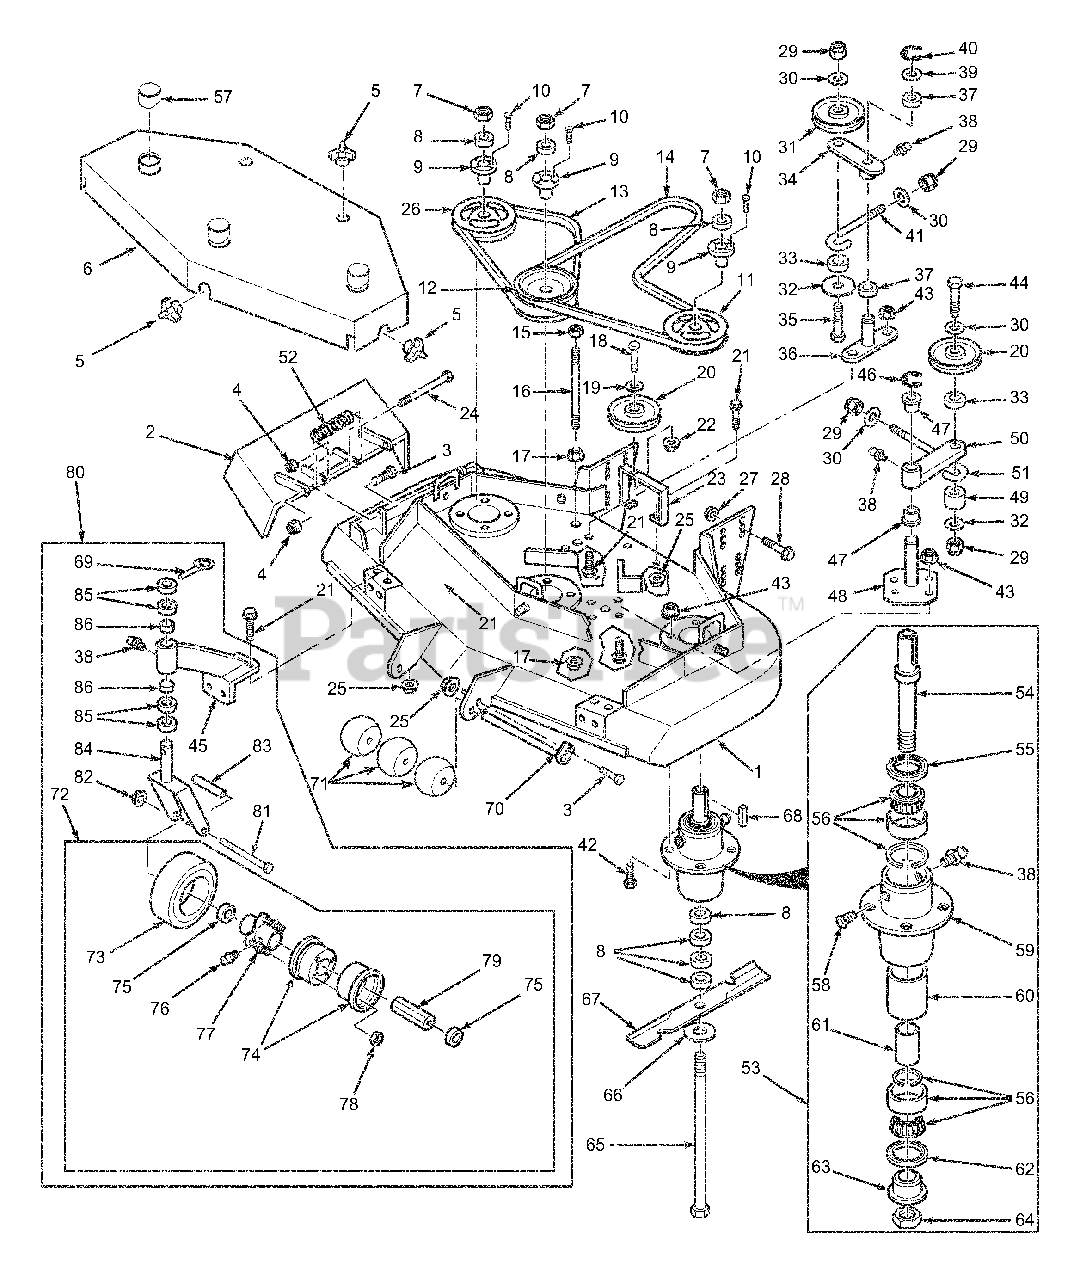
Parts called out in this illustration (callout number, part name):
1	Cutter Deck, Advantage
2	Discharge Chute, Advantage
3	Bolt, 5/16-18 x 1" Hex Head
4	Nut, 5/16-18 Elastic Stop
5	Wing Nut, 3/8-16
6	Belt Cover
7	Nut, 5/8-11 Hex Head
8	Spacer, Cutter Blade
9	Tapered Hub, 1.125 Bore
10	Bolt, 1/4-20 x 3/4 Hex Head
11	Pulley, 6.35 O.D.
12	Pulley, Double Groove, 6.35/5.75 O.D.
13	Belt, R.H. Blade Drive
14	Belt, Deck Drive
15	Lock Nut,3/8-16 Hex Head
16	Stud, 3/8-16 x 6-3/4"
17	Nut, 3/8-16 Serr. Flange
18	Bolt, 3/8-16 x 2-1/4"
19	Flatwasher, 3/8 (.391 x .938 .105)
20	Pulley, Belt Guide
21	Capscrew, 5/16-18 x 3/4 Ser. Flg. HH
22	Nut, 3/8-16 Elastic Stop
23	Idler Pulley Support
24	Bolt, Hex Head 5/16-18 x 4-1/4"
25	Nut, 5/16-18 Ser. Flg. Hex Hd.
26	Pulley, 5.75
27	Nut, 1/2-13 Ser. Flg. Hex Hd.
28	Capscrew, 1/2-13 x 1-1/4 Ser. Flg.
29	Nut, 3/8-16 Elastic Stop
30	Flatwasher, 3/8 (.391 x .938 x .105)
31	Pulley
32	Flatwasher, 3/8 (.375 x 1.50 x .060)
33	Spacer
34	Idler Arm
35	Bolt, 3/8-16 x 2-1/4"
36	Idler Pivot
37	Bushing, Bronze Oilite-3/4 ID
38	Grease Fitting, Str. 1/4-28 Self Tap.
39	Flatwasher, 3/4 (.776 x 1.25 x .059)
40	Retaining Ring, .75 EXT 'E'
41	J-Rod Idler Pulley
42	Bolt, 5/16-18 x 1-1/4" Hex Head
43	Nut, 5/16-18 Ser. Flange
44	Bolt, 3/8-16 x 3-1/2" Hex Head
45	Support Assembly
46	Retaining Ring, 1-1/8 EXT 'E'
47	Bushing, Bronze Oilite- 1-1/8 ID
48	Idler Pivot Support
49	Spacer
50	Idler Arm
51	J-Rod, Drive Idler
52	Spring, Chute Return
53	Spindle Assembly
54	Shaft, Cutter Spindle
55	Seal, 2.00 O.D. x 1.50 Bore
56	Bearing Assembly
57	Shield, Spindle
58	Relief Fitting, Cutter Spindle
59	Spindle Housing
60	Spacer, Outside
61	Spacer, Inside
62	Seal, 2.00 O.D. x 1-5/8 Bore
63	Spindle Bushing Bottom
64	Nut, 1-1/16-18 UNEF-2B
65	Bolt, 5/8-11 x 9-1/2"
66	Flatwasher, 5/8 (.688 x 1.75 x .134)
67	Cutter Blade, 21" Standard
68	Key, 1/4 x 1/4 x 2"
69	Quick Pin
70	Shaft, Roller
71	Guide, Roller
72	Wheel Assy., Caster
73	Tire Only, Caster Wheel
74	Rim Pair, Caster Wheel
75	Retainer, Caster Wheel
76	Grease Fitting, 45 Deg. 1/4-28
77	Hub Assy. W/Bolts, Caster Wheel
78	Tapered Hex Nut, 5/16-18
79	Roller Bearing, Caster Wheel
80	Caster Wheel Assembly
81	Bolt, 1/2-13 x 5-1/2" Hex Head
82	Nut, 1/2-13 Elastic Stop
83	Sleeve, Caster Wheel Bearing
84	Caster Yoke
85	Spacer, Caster Yoke 1/2"
86	Bushing, 7/8 x 1" Flanged
